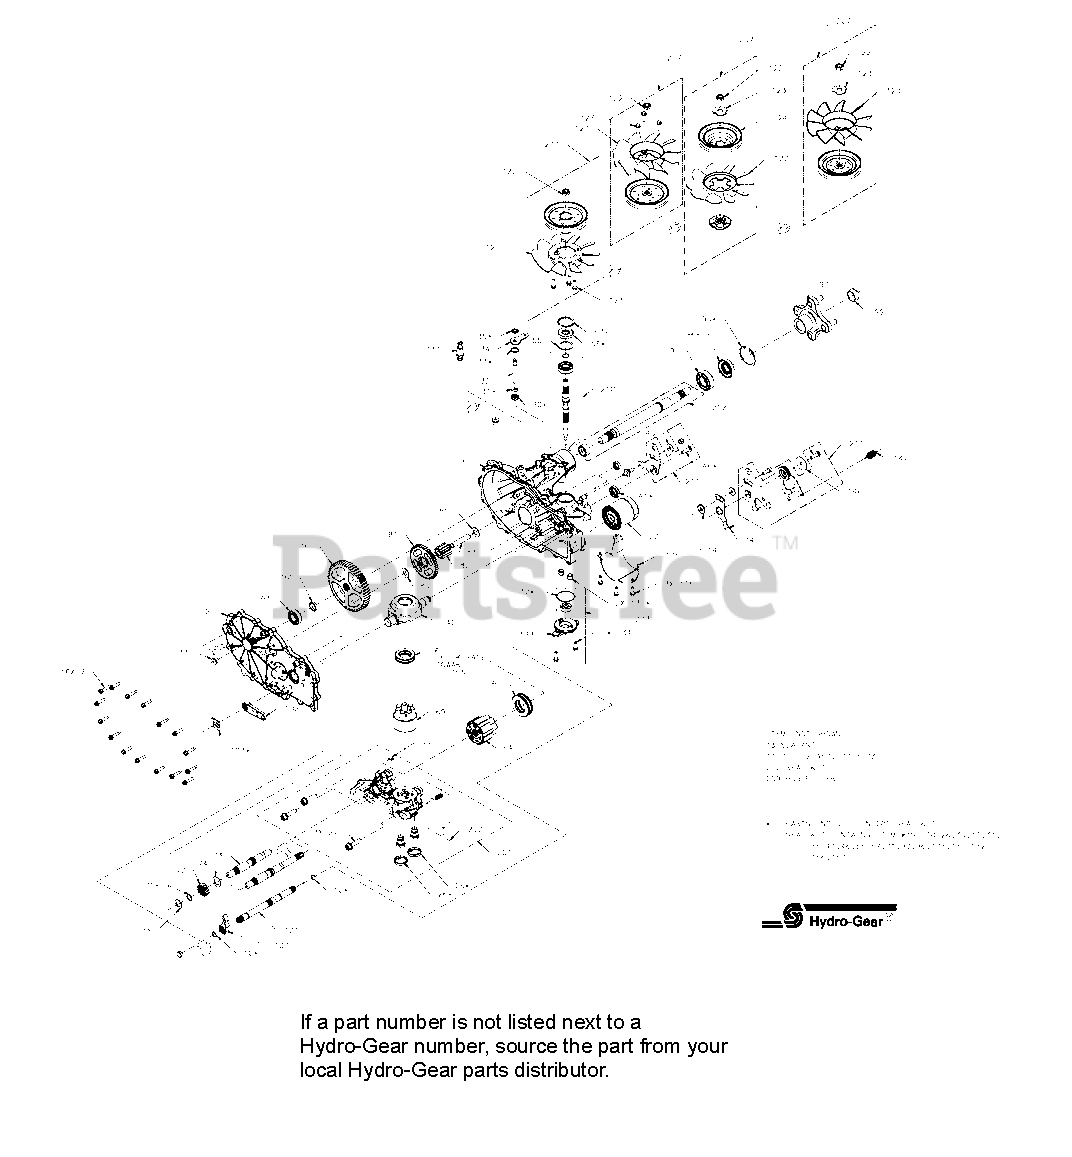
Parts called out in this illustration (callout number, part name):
1	KIT, HOUSING, MAIN, RH, CHRG, CNTL
7	HFHCS 1/4-20 x 1.125"
10	O-RING - 111 .103 x .424
11	PLUG 9/16-18 (METAL)
13	SEALANT
14	OIL, 20W50
22	PLATE, BYPASS
23	FILTER, OIL
26	SEAL, PLUG 1.250 x .250
27	HFHCS 3/8-16 x 1.5 (PATCH)
30	SEAL, LIP .375 x .75 x .25
31	RING, RET .375 EXTRNL
32	ROD, BYPASS
33	RING, RET .750 INTRNL
34	ARM, BYPASS
35	RING, RTNG .375 EXT
40	TRUNNION, SWASHPLATE
41	SEAL, LIP 12 x 32 x 7
45	WASHER .34 x .88 x .06
46	TWHCS 5/16-24 x 1.00 (PATCH)
55	WASHER 1.23 x 1.56 x .04
56	SEAL, LIP 17 x 40 x 7
57	RING, RETAINING
60	BEARING, THRUST
64	ASS'Y, CYLINDER BLOCK, 16cc
65	BRG, THRUST BALL 30 x 52 x 13
69	ASS'Y, BLOCK 7 PISTON
70	WASHER .63 x 1.0 x .05
71	RING, RETAINING_.625
72	GEAR, 16T
73	SHAFT, MOTOR
74	WASHER .72 x 1.16 x .04
80	WASHER .5 x 1.0 x .03
81	GEAR, 43T
82	GEAR, 11T
83	JACK SHAFT (PIN)
90	RING, RET 2.06 INT
91	GEAR, 54T
92	SPACER, .75 x 1.32 x .257
93	BEARING, BALL, .75 x 40 x 12
95	BRG, BALL 1.0 x 52 x 15 OPEN 6205M
96	SEAL, LIP 25 x 52 x 10 TC (GRAY)
97	KIT, HUB, 4 BOLT
99	NUT, HEX LOCK 3/4-16
100	PAWL, BRAKE
101	SHAFT, BRAKE
102	HANDLE, ACTUATING
103	CLIP, RETAINING
105	HFHCS 1/4-20 x .75
106	GUARD, FILTER, RH
111	FITTING, STR 9/16-18 SAE .5 BARB
122	NUT, HEX JAM 1/2-20 W/PATCH
123	HFHCS 1/4-20 x .875
130	TUBE, CONNECTING
131	GEROTOR ASSEMBLY (1.9 cc/rev)
132	O-RING, -137, 0.103 x 2.050
133	COVER, CHARGE PUMP
134	HFHCS 1/4-20 x .75
140	SPACER .320 x 1.005 x .179
141	ARM, NEUTRAL RIGHT
142	SHCS 5/16-24 x 1 PATCH
146	WASHER, .343 x 1.500 x .062
147	SPRING, EXTNSN RTN-34LBS
200	KIT, SEAL
201	KIT, CENTER SECTION, RH, CHRG
202	KIT, CHARGE RELIEF
203	KIT, CHARGE PUMP
207	KIT, FAN & PULLEY
209	UB PULLER, 4 BOLT
210	KIT, INPUT SHAFT
211	KIT, RTN, CW
212	KIT, SHAFT, AXLE
